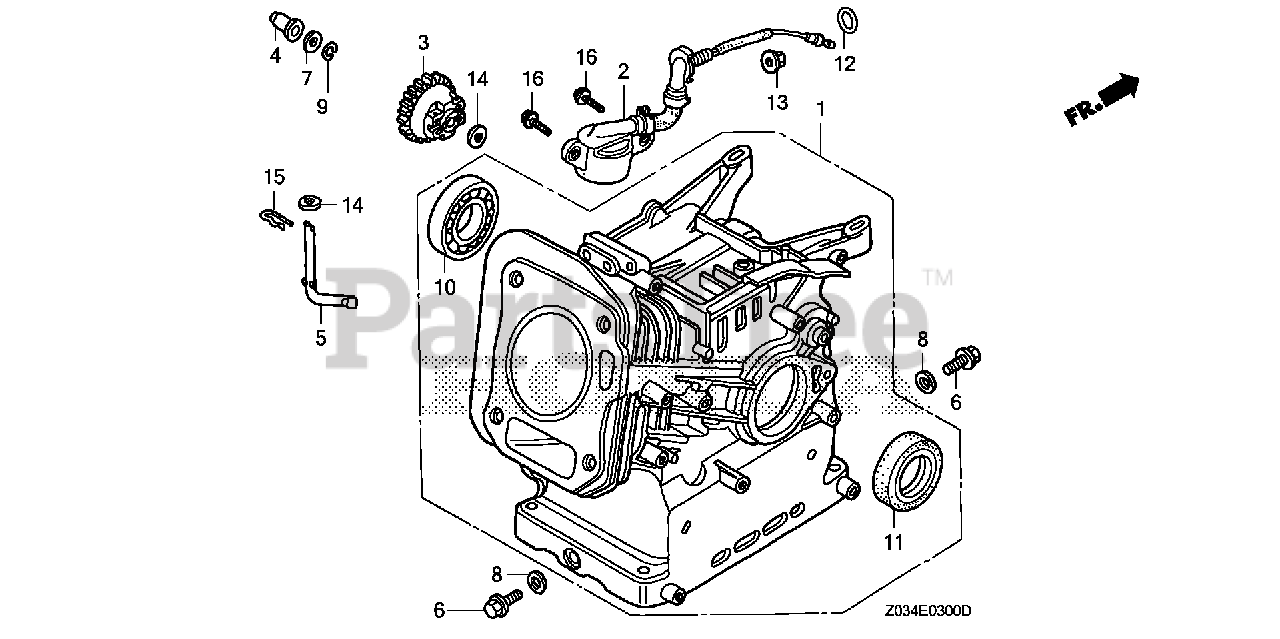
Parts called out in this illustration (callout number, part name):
1	CYLINDER ASSY. (OIL ALERT)
2	SWITCH ASSY., OIL LEVEL
3	GOVERNOR ASSY.
4	SLIDER, GOVERNOR
5	SHAFT, GOVERNOR ARM
6	BOLT, DRAIN PLUG
7	WASHER, THRUST (6MM)
8	WASHER, DRAIN PLUG (10.2MM)
9	CLIP, GOVERNOR HOLDER
10	BEARING, RADIAL BALL (6205TMB) (NTN)
10	BEARING, RADIAL BALL (6205) (NSK)
11	OIL SEAL (25X41X6) (NOK)
12	O-RING (13.5X1.5) (ARAI)
12	O-RING (14MM) (NOK)
13	NUT, FLANGE (10MM)
14	WASHER, PLAIN (6MM)
15	PIN, LOCK (8MM)
16	BOLT, FLANGE (6X12)
